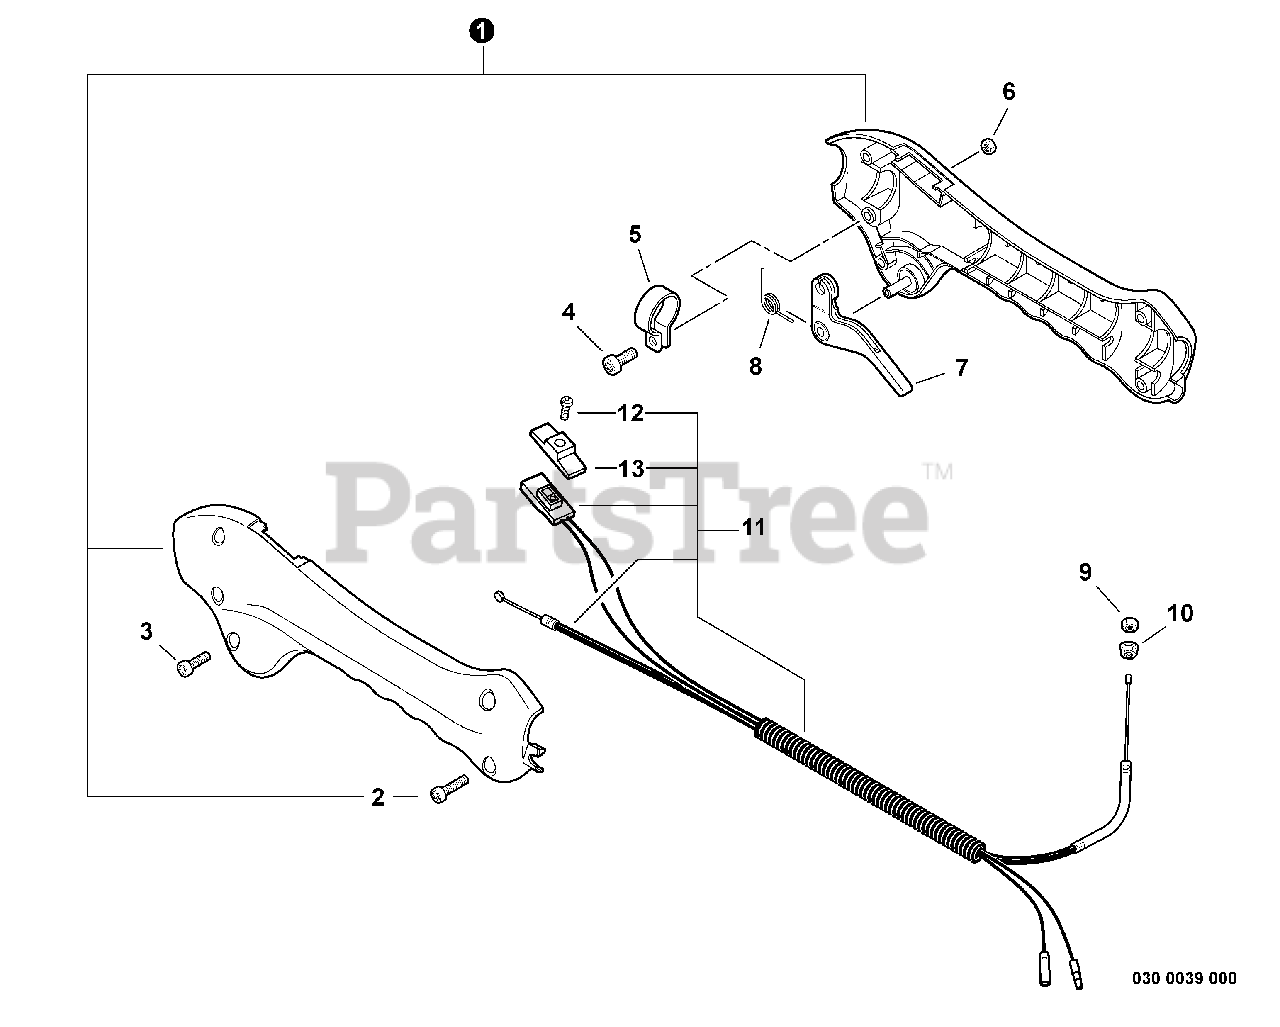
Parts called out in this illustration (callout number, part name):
1	CONTROL HANDLE KIT
2	BOLT, TORX 4×16
3	BOLT, TORX 4×12
4	BOLT, TORX 5×12
6	NUT M5
7	TRIGGER, THROTTLE
8	SPRING, TORSION
10	NUT, FLANGE M6×1
11	CABLE ASSY, CONTROL
12	SCREW 3×10
13	KNOB, SWITCH - ORANGE
